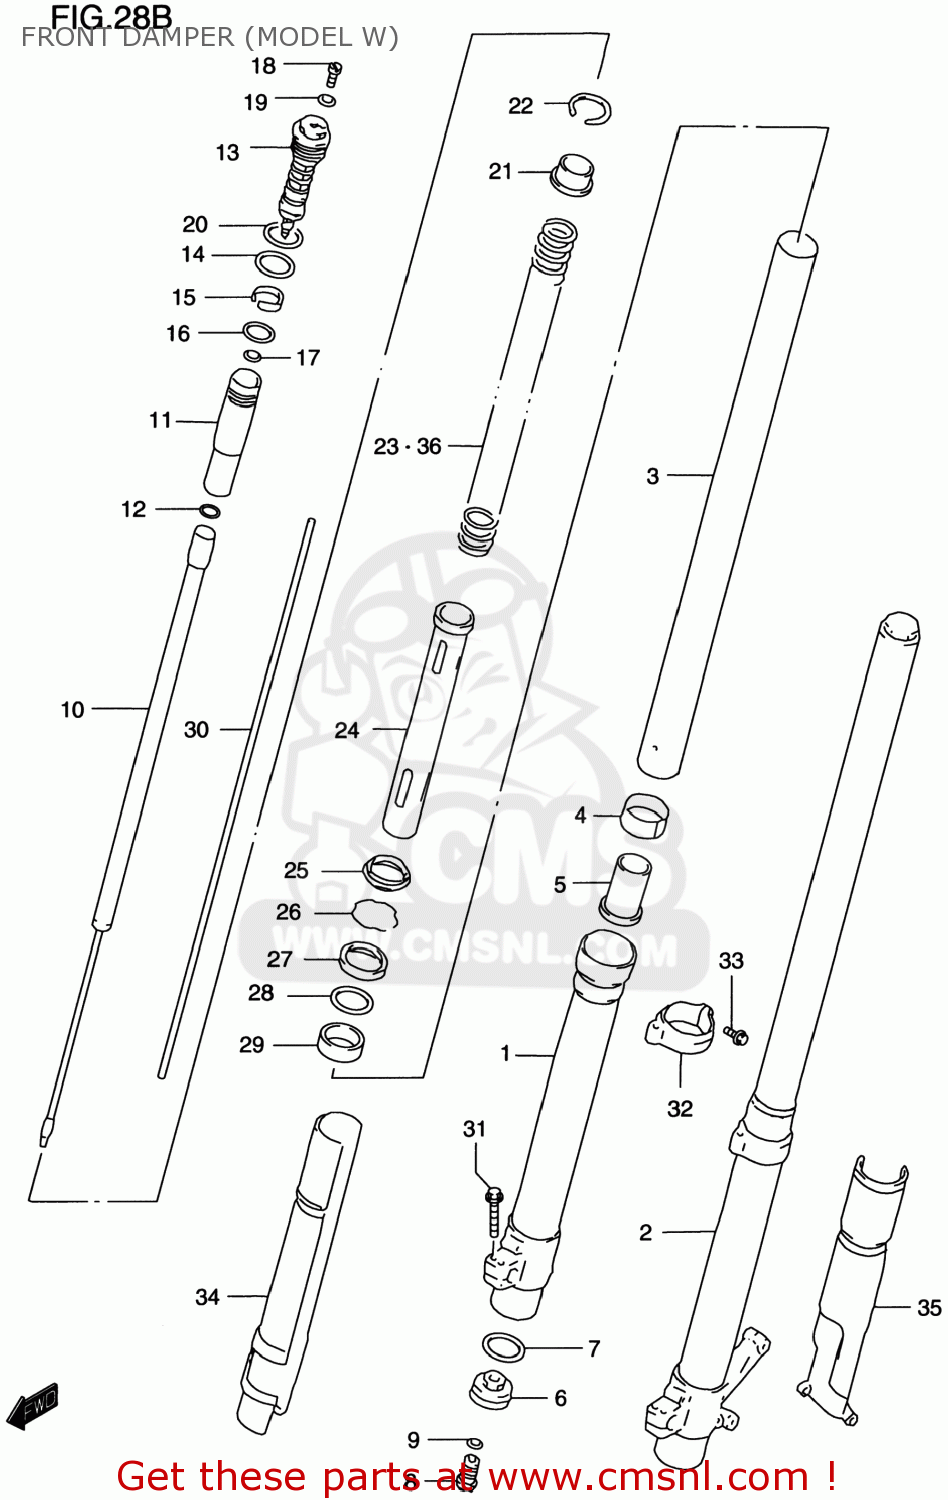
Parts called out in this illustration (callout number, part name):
1	TUBE,OUTER,R
2	TUBE,OUTER,LEFT
3	TUBE,INNER
4	BUSH,SLIDE
5	PIECE,OIL LOCK
6	PLATE,END
7	O RING
8	BOLT,CTR
9	O RING,CTR BOLT
10	ROD,FRONT DAMPER
11	TANK,SUB
12	O-RING
13	BOLT,FORK
14	O RING
15	BUSHING,SLIDE
16	O RING
17	O RING
18	BOLT,PLUG
19	O RING,PLUG
20	O RING
21	SPRING,STOPPER
22	RING,STOPPER
23	SPRING,FRONT (K=0.40)
24	COLLAR,SPRING
25	SEAL,DUST
26	RING,STOPPER
27	SEAL,OIL
28	SPACER,SEAL
29	BUSH,GUIDE
30	ROD,PUSH
31	BOLT,HANDLE HOLDER(8X35)
32	GUIDE,FR PROTECTOR,R
33	BOLT
34	PROTECTOR,OUTER TUBE,R
35	PROTECTOR,OUTER TUBE,L
36	SPRING,FRONT (K=0.38)
